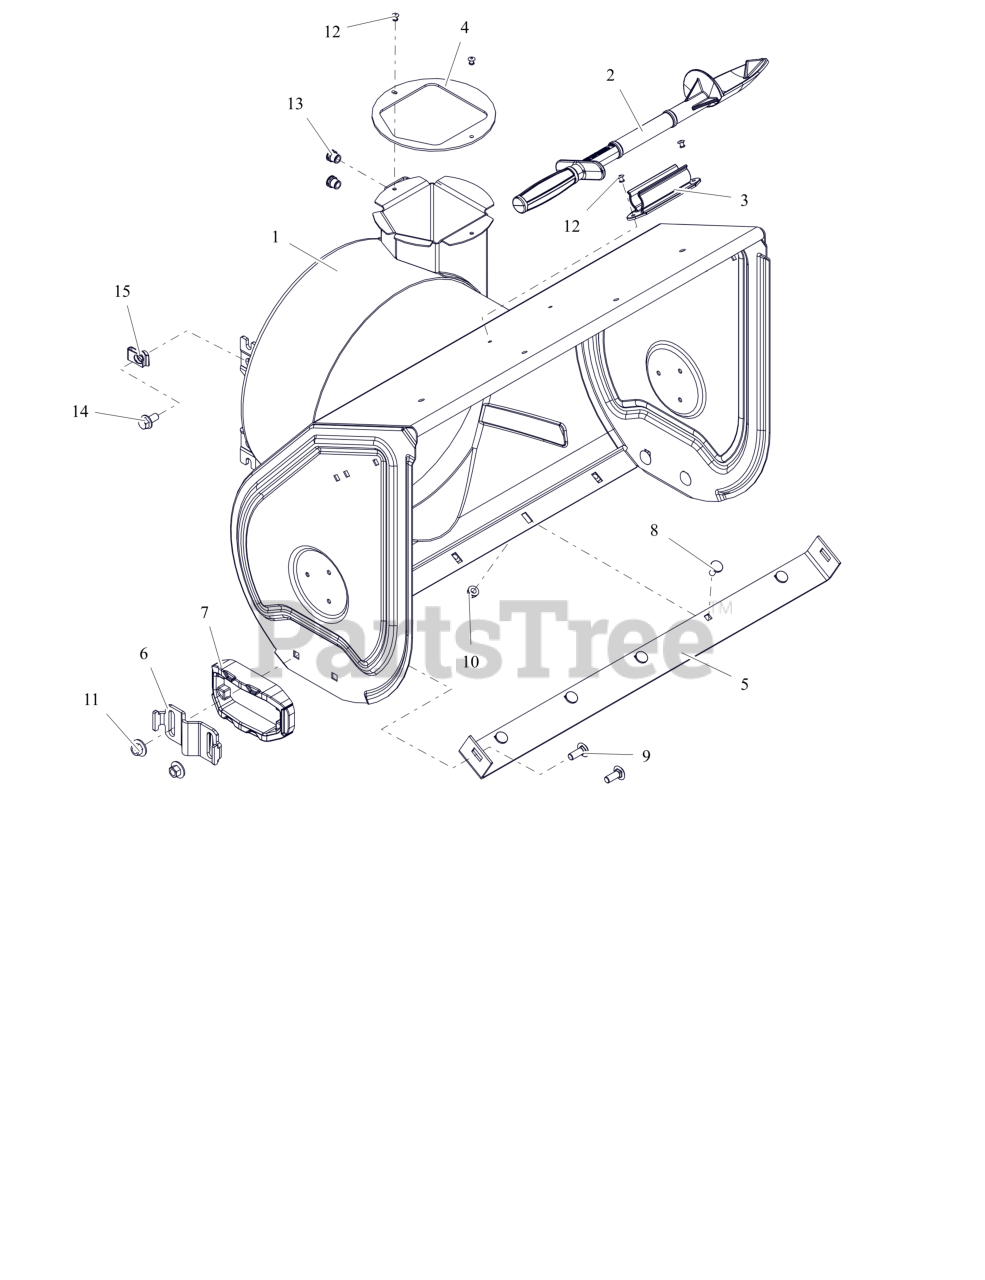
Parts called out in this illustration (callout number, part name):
1	HOUSING, BLOWER W/DECALS 28"
2	DEVICE, SNOW CLEAN OUT
3	MOUNT, SNOW CLEAN OUT
4	BAFFLE, DISCHARGE NECK
5	BLADE, SCRAPER - 28"
6	SHOE, SKID - INSERT (BLACK)
7	SHOE, SKID - WEAR
8	BOLT, MODIFIED HEAD CARRIAGE
9	BLT,RHSSN .38-16X1.00 G5 ZCC
10	NUT-LK-TOP-FLG .312-18 GF ZCC
11	NUT- CON-LN .375-16 ZC120
12	RVT, POP .1875 ZCC
13	NUT,THD,INSERT .38-16 ZC120
15	NUT-RTNR .375-16X.37
